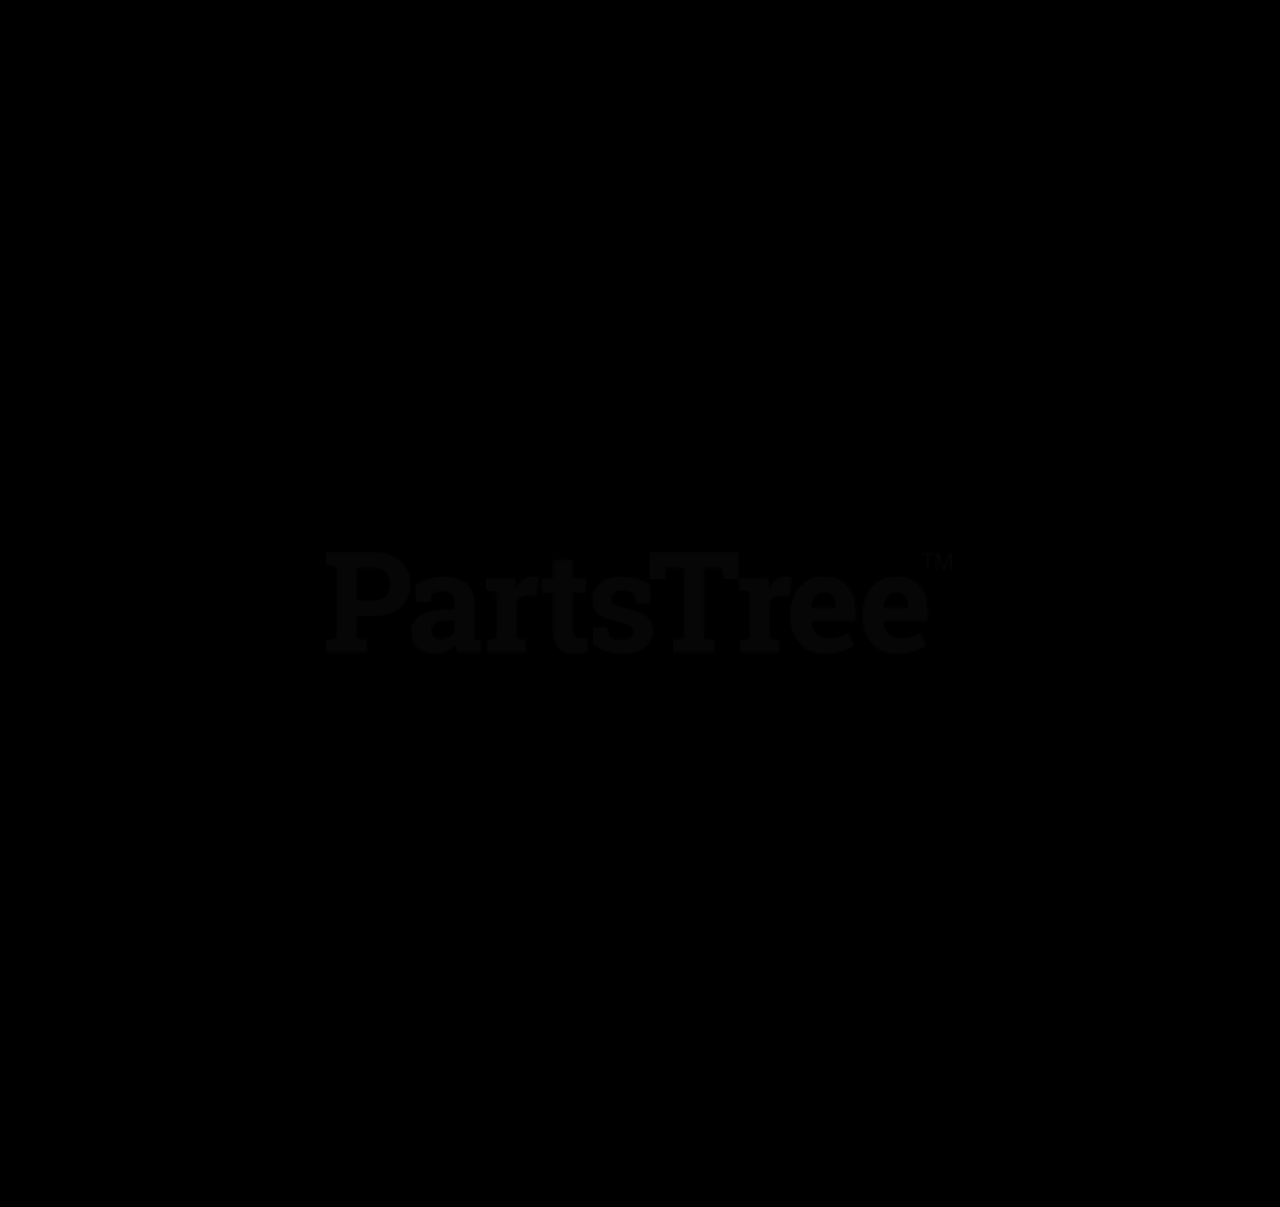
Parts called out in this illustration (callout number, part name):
1	Seal, Trim-LOK Bulk .06 Bubble
2	Weldment, Radiator Shroud
3	Bolt, Hex .38-16 x 1.00 Grade 5
4	Washer, Locking .25 x .062 Regular
5	Bolt, Hex .25-20 x .75 Grade 5
6	Bracket, Radiator Mounting
7	Hose, .31 ID
8	Clamp, Fuel Line
9	Radiator (Comes with the engine)
10	Screen, Radiator
11	Spacer .328 x .76 x 1.01
12	Nut, Locking Top Flange .38-16
13	Nut, Locking Top Flange .25-20
14	Bracket, Overflow Mounting
15	Screw, Tapping .38-16 x .75 Hex Washer Head
16	Reservoir Overflow (Comes with the engine)
17	Bolt, Hex M6-1.00 x 45
18	Washer, Flat Steel .281 x .62 x .065
19	Bolt, Hex M6-1 x 16
